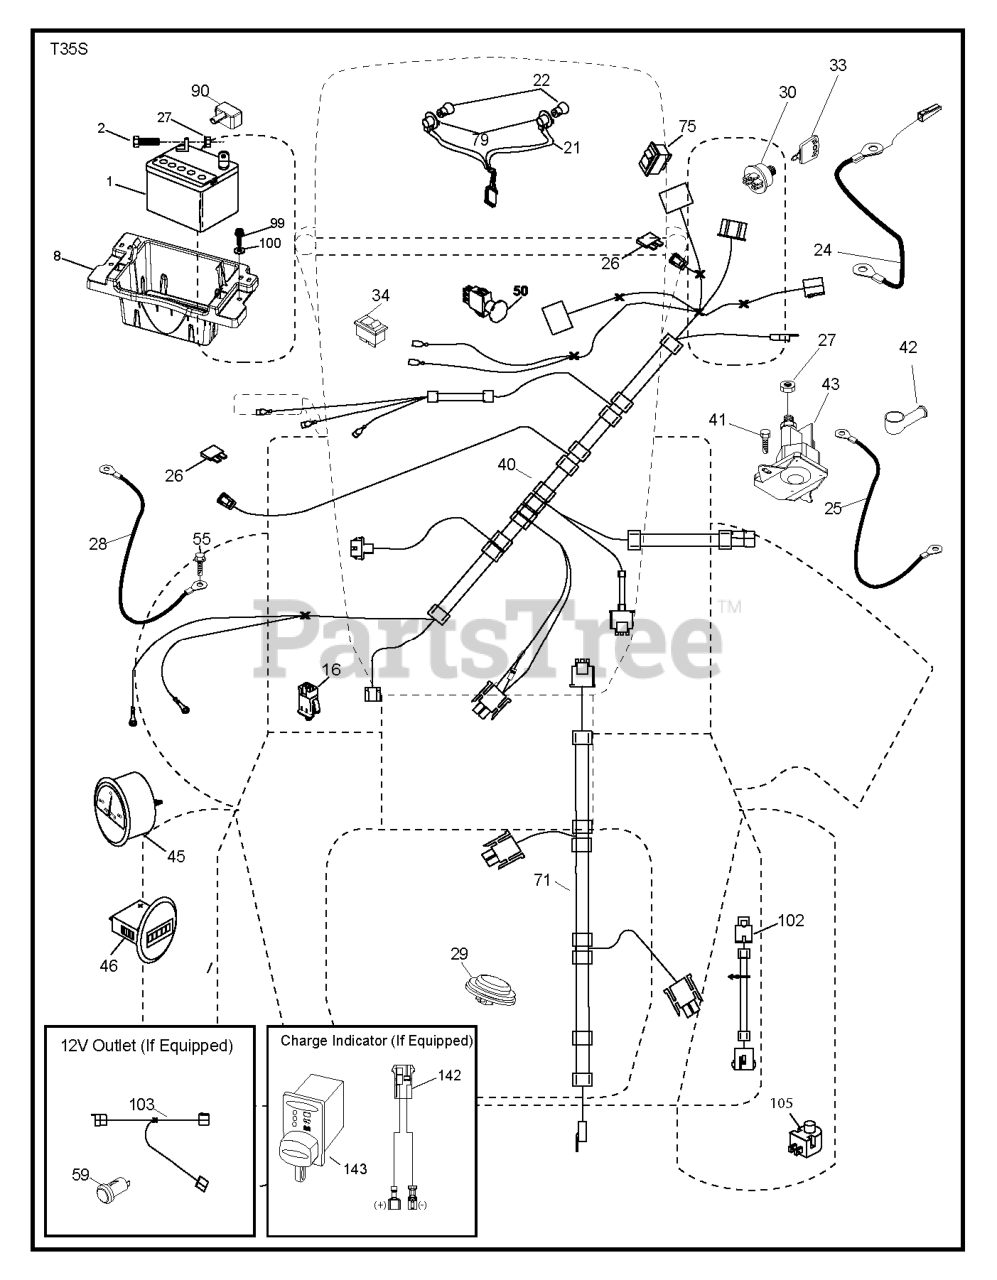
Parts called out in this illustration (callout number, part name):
1	Battery 12 Volt 25 Amp
2	BOLT.HEX.1/4.X.3/4.DICHROMATE
8	TRAY.BATTERY BOX.FRONT
16	SWITCH INTERLOOK PUSH-IN
21	HARNESS.LIGHT W/4152J BULBS
24	CABLE.FRBATT.W/WIRE.8GA.8
25	CABLE.STARTER.8GA.17.5
26	FUSE 20AMP
27	NUT
28	CABLE.GROUND.21"BLK.8GA.90T
29	SWITCH.SEAT.DELTA.OPC.
30	SWITCH.IGN.DELTA.W.LGH.ROS
33	KEY.CHAIN.BLISTER.PACK.GEN.USA
40	HARNESS.DASH.EDIFF.RND.CHG
41	SCREW
42	TERMINAL COVER
43	SOLENOID.STARTER.BRASS.PLUNGER
45	GAUGE.AMMETER.SILVER/WHITE
46	GAUGE.HOUR.METER.SILVER/WHITE
50	SWITCH.PTO.8TERMINAL.STD.BLK
55	SCREW 5/16"
59	OUTLET.12-VOLT
71	HARNESS.IGN.CHASSIS.TEX.DCKLOC
75	SWITCH.ON/OFF.(DIFF.LOCK)
79	BULB HOLDER ASM.
90	COVER.TERMINAL.BATTERY
99	SCREW HEXWSHR 1/4-20X3/4
100	WASHER
102	HARNESS PIGTAIL PCH TEX ROS
103	HARNESS.PIGTAIL.12V.OUTLET.
105	REVERSE SWITCH
142	CHARGE.PORT.PIGTAIL HARNESS
143	CHARGE.PORT
